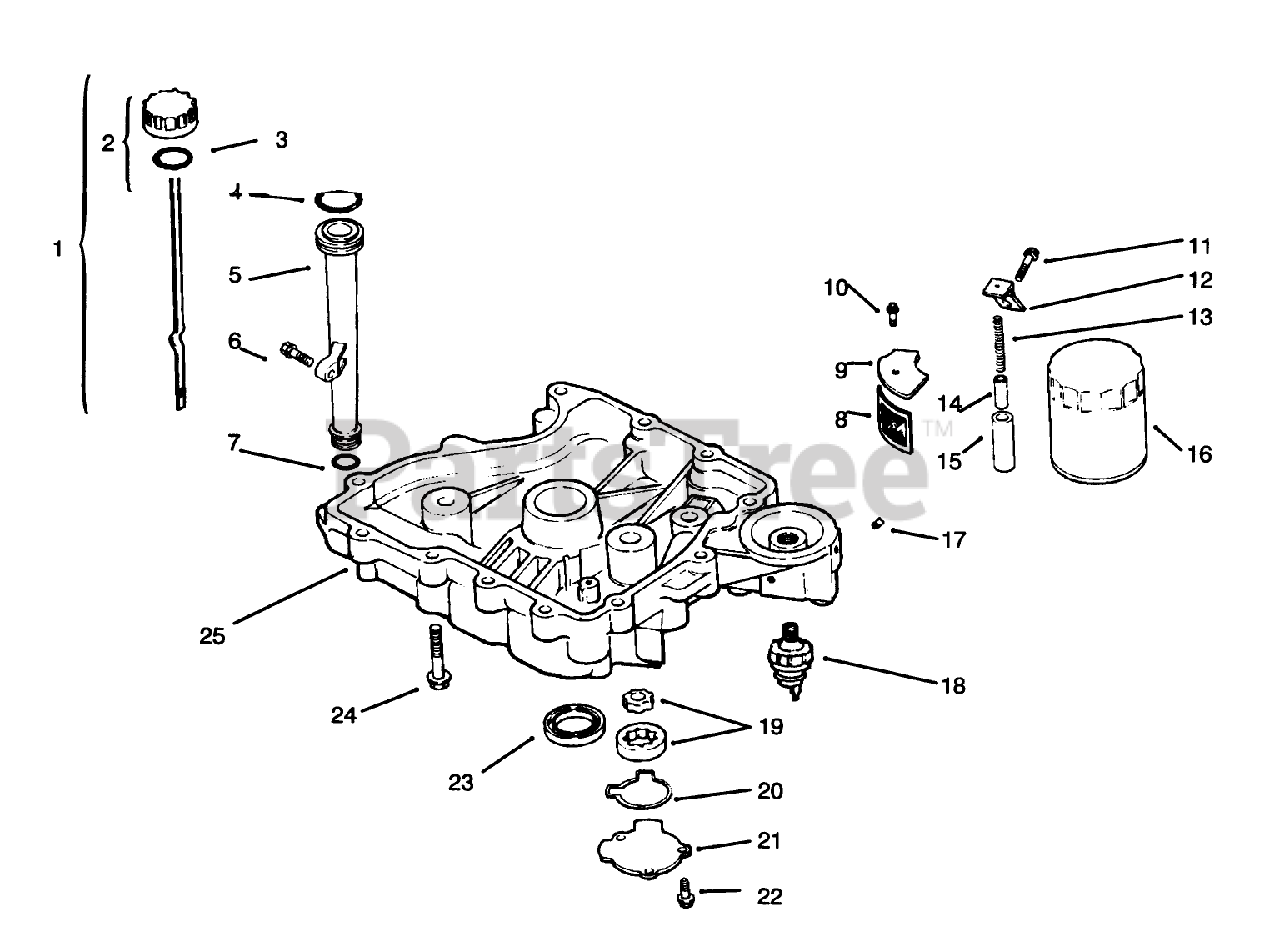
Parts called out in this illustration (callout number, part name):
1	Dipstick INC 2-3 (Only On: 72042, 72063, 72062, 72043)
2	Kit-Oil Fill Cap (Incl. Ref. #7)
3	ORing
4	O Ring-Upper Fill Tube (Only On: 72103)
5	Tube-Oil Fill (Only On: 72103, 72083)
7	O-Ring-Lower Fill Tube (Only On: 72042, 72063, 72062, 72043)
8	Screen-Oil Pickup (Only On: 72042, 72063, 72062, 72043)
9	Cover-Oil Pickup Screen (Only On: 72042, 72063, 72062, 72043)
10	Screw M5x0.8x16 (Only On: 72042, 72063, 72062, 72043)
11	Screw M10x1.5x25 (Only On: 72042, 72063, 72062, 72043)
12	Bracket-Oil Pump Relief (Only On: 72042,72043,72062,72063)
13	Spring-Oil Relief Valve (Only On: 72042,72043,72062,72063)
14	Piston-Oil Relief Valve (Only On: 72042, 72063, 72062, 72043)
15	Body-Oil Relief Valve (Only On: 72042, 72063, 72062, 72043)
16	Filter-Oil
18	Switch-Oil Pressure
19	Pump-Oil (Only On: 72042, 72063, 72062, 72043)
20	O Ring-Oil Pump Cover (Only On: 72042,72043,72062,72063)
21	Cover-Oil Pump (Only On: 72042,72043,72062,72063)
22	Screw M5x0.8x16 (Only On: 72042, 72063, 72062, 72043)
23	Seal-Crankshaft (Only On: 72042, 72043, 72062, 72063)
24	Screw M8x1.25x45 (Only On: 72042, 72063, 72062, 72043)
25	Pan-Oil
